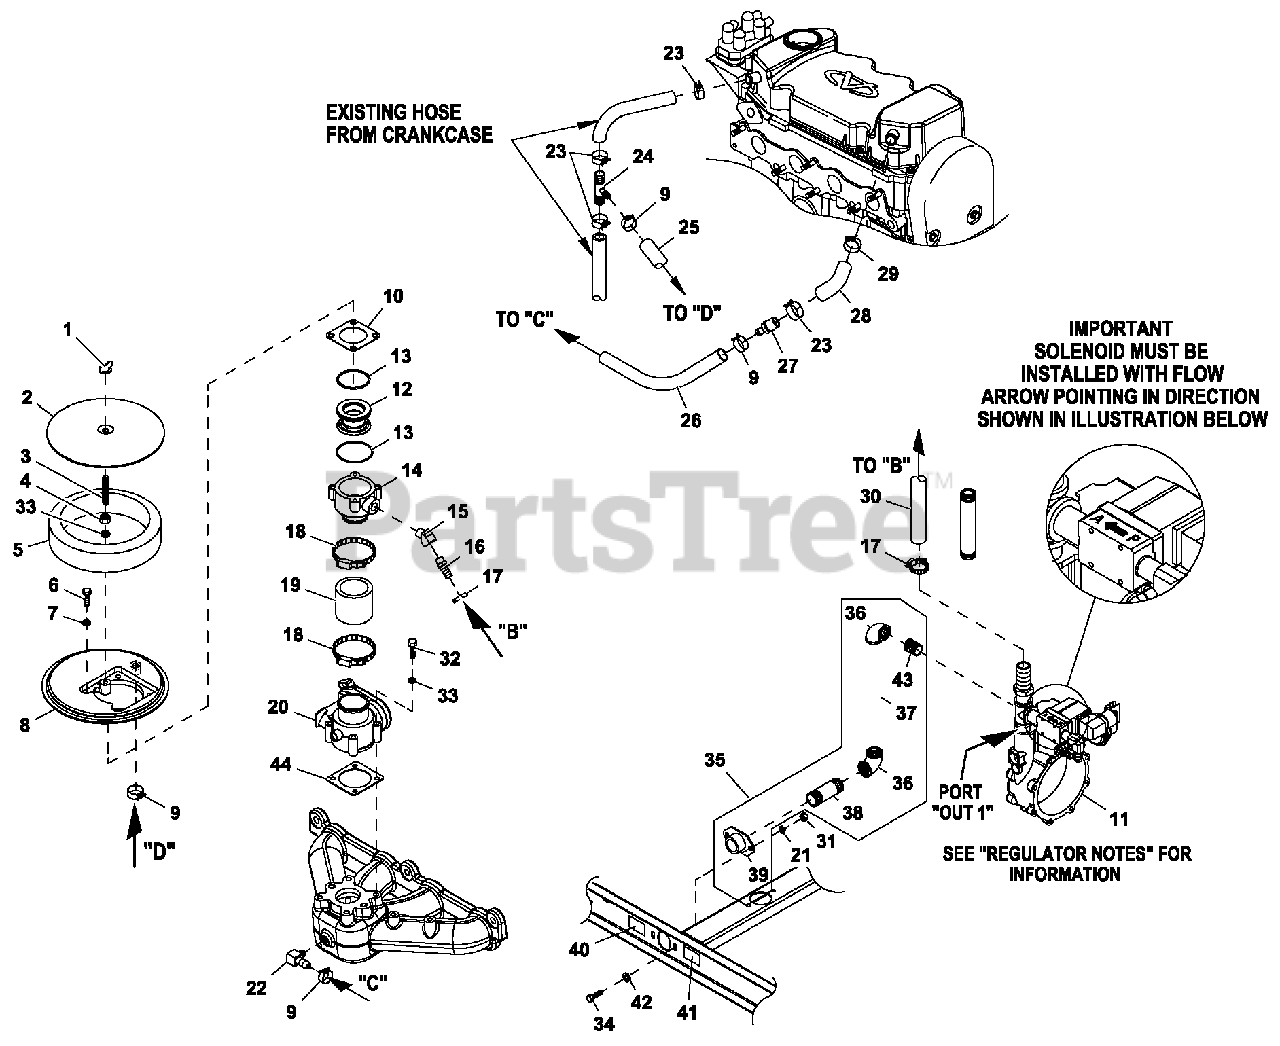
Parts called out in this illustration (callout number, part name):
1	NUT WING 1/4-20 NYLK
2	COVER AIR CLEANER
3	STUD TH 1/4-20 X 3 G2 ZNC F ULL
4	NUT HEX 1/4-20 STEEL
5	FILTER ELEMENT
6	SCREW PPHM M5-0.8 X 12 ZNC
7	WASHER LOCK M5
8	ADAPTER, CARBURETOR W/PVC CONN
9	CLAMP HOSE BAND .63
10	GASKET BOSCH 32 & 40
11	FUEL REG. REWORK 1.6L
12	VENTURI THROTTLE 21 MM
13	O-RING 47.625 ID X 2.38 WIDTH
14	MIXER ACTUATOR 32MM MACHINED
15	STREET EL 45D 1/2 NPT BRASS
16	BARBED STR 1/2 NPT X 3/4
17	CLAMP HOSE #10 .56-1.06
18	CLAMP HOSE #28 1.32-2.25
19	HOSE 1.5 ID X 2 LG 20R4
20	ACTUATOR BOSCH 32 GOVERNOR
21	WASHER LOCK M8-5/16
22	BARBED EL 90 1/8 NPT X 3/8
23	CLAMP HOSE BAND 1.0"
24	HOSE BARB REDUCR TEE 3/4"-3/8"
25	HOSE 3/8 ID SINGLE BRAID (11.5" LG)
26	HOSE 3/8 ID SINGLE BRAID (12" LG)
27	PCV VALVE 2.5L F ORD
28	HOSE BREATHER 1.6L
29	CLAMP HOSE BAND .88"
30	HOSE 3/4 ID LPG & NG (16"LG)
31	NUT HEX M8-1.25 G8 YEL CHR
32	SCREW HHC M6-1.0 X 45 C8.8 FTH
33	WASHER LOCK M6-1/4
34	SCREW HHC M8-1.25 X 20 G8.8
35	ASSY REG INLET NPT FITTINGS
36	ELBOW 90D 3/4 NPT
37	NIPPLE PIPE 3/4NPTX4.5 BLK IRN
38	NIPPLE PIPE 3/4NPT X 2
39	FLANGE FUEL INLET
40	DECAL INLET PRESSURE
41	DECAL FUEL INLET
42	WASHER FLAT 5/16 ZINC
43	NIPPLE CLOSE 3/4X1.375
44	GASKET BOSCH 32
